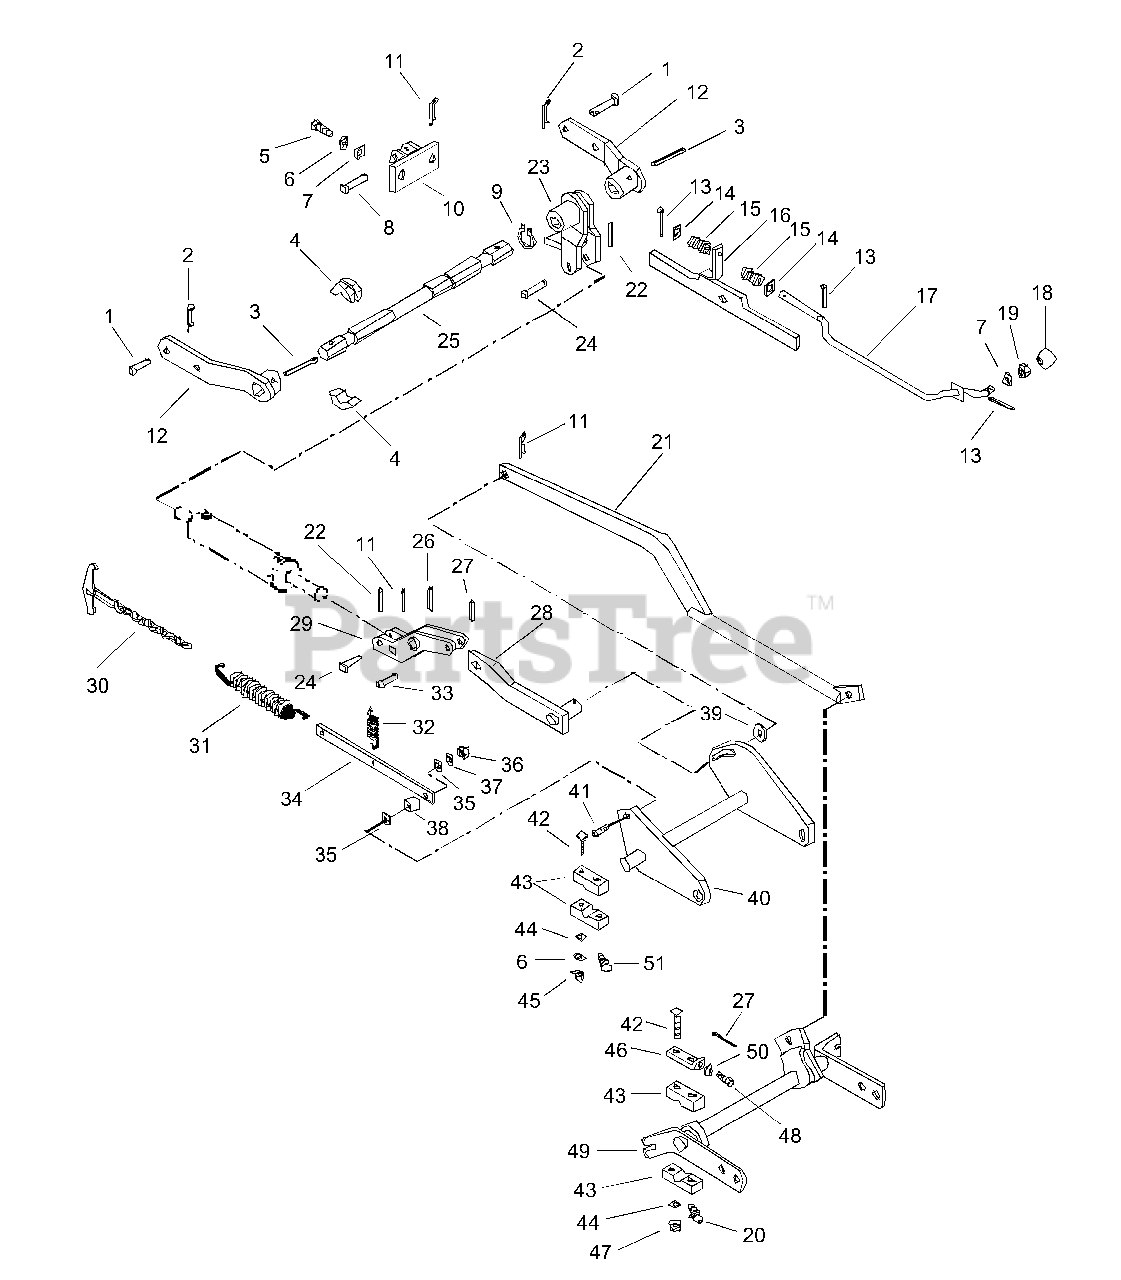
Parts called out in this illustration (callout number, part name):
1	Rivet .50 x 1.25
2	Pin-Hair Internal .15 x .43 x 2.75
3	Pin-Cotter .18 x 2.0
4	Bushing-Flange 1.000 x 1.75 x 1.000
5	Bolt-Hex .38-16 x 1.00 Grade 5
6	Washer-Lock .38 x .094
7	Washer-Flat-Steel .438 x 1.0 x .083
8	Clevis Pin .616/.621 x 2
9	Ring-Retaining-External 1.125 x .050
11	Pin-Hair Internal .09 x .188 x 2.00
12	Arm
13	Pin-Cotter .12 x .75
14	Washer-Flat-Steel .406 x .812 x .065
15	Spring-Compression .65 x .56 x 1.50
16	Latch
17	Latch Rod
18	Knob - Steering Lock
19	Nut-Hex .375 - 16
20	Fitting-Lube .25-28 x .256
21	Link - Connector
22	Pin-Cotter .12 x 1.0
23	Arm
24	Clevis Pin .491/.496 x 1 15/16
25	Shaft
26	Pin - Cotter .18 x 1.25
27	Pin-Cotter .18 x 1.0
28	Link
29	Bellcrank
30	Chain
31	Spring-Tension .156 x 1.062 x 2.68
32	Spring-Tension .035 x .45 x 2.75
33	Clevis Pin .616/.621 x 1.42/1.44
34	Link
35	Washer-Flat-Steel .281 x .620 x .065
36	Nut-Hex .250 - 20
37	Washer-Lock .250 x .077
38	Spacer .269
39	Washer-Flat-Steel .812 x 1.500 x .139
40	Center Rockshaft
41	Bolt-Hex .25-20 x 1.00 Grade 5
42	Bolt-Round Head Square Neck .38-16 x 2.25 Grade 5
43	Block
44	Washer-Flat-Steel .406 x .750 x .005
45	Nut-Hex .38-16 Grade 2
46	Brace
47	Nut-Locking-Center .38-16
48	Bolt-Hex .31-18 x 1.25 Grade 5
49	Rock-Shaft Front
50	Washer-Lock .312 x .097
